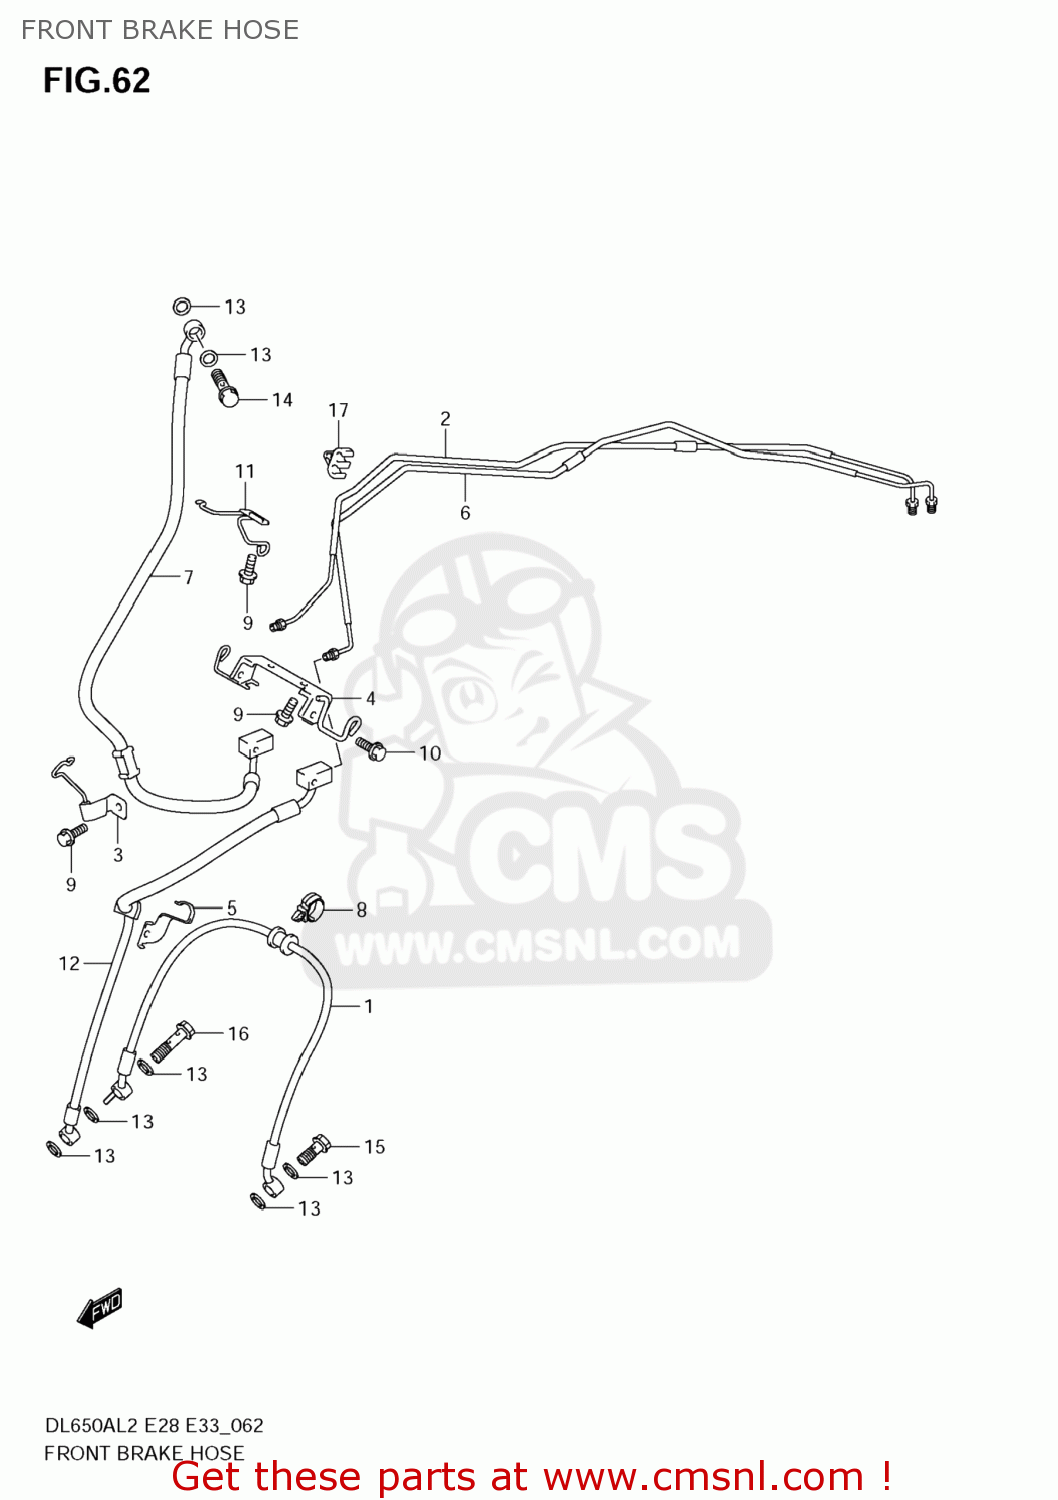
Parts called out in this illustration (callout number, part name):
1	HOSE,FR BRAKE NO.2
2	PIPE,FR BRAKE NO.1
3	CLAMP,FR BRAKE HOSE
4	CLAMP,FR BRAKE HOSE NO.2
5	CLAMP,FR BRAKE HOSE,R
6	PIPE,FR BRAKE NO.2
7	HOSE,FR BRAKE NO.1
8	CLAMP
9	BOLT
10	BOLT
11	GUIDE,FR BRAKE HOSE
12	HOSE,FR BRAKE NO.3
13	WASHER(10X15X1.5)
14	BOLT UNION
15	BOLT UNION
16	BOLT UNION
17	CLAMP
